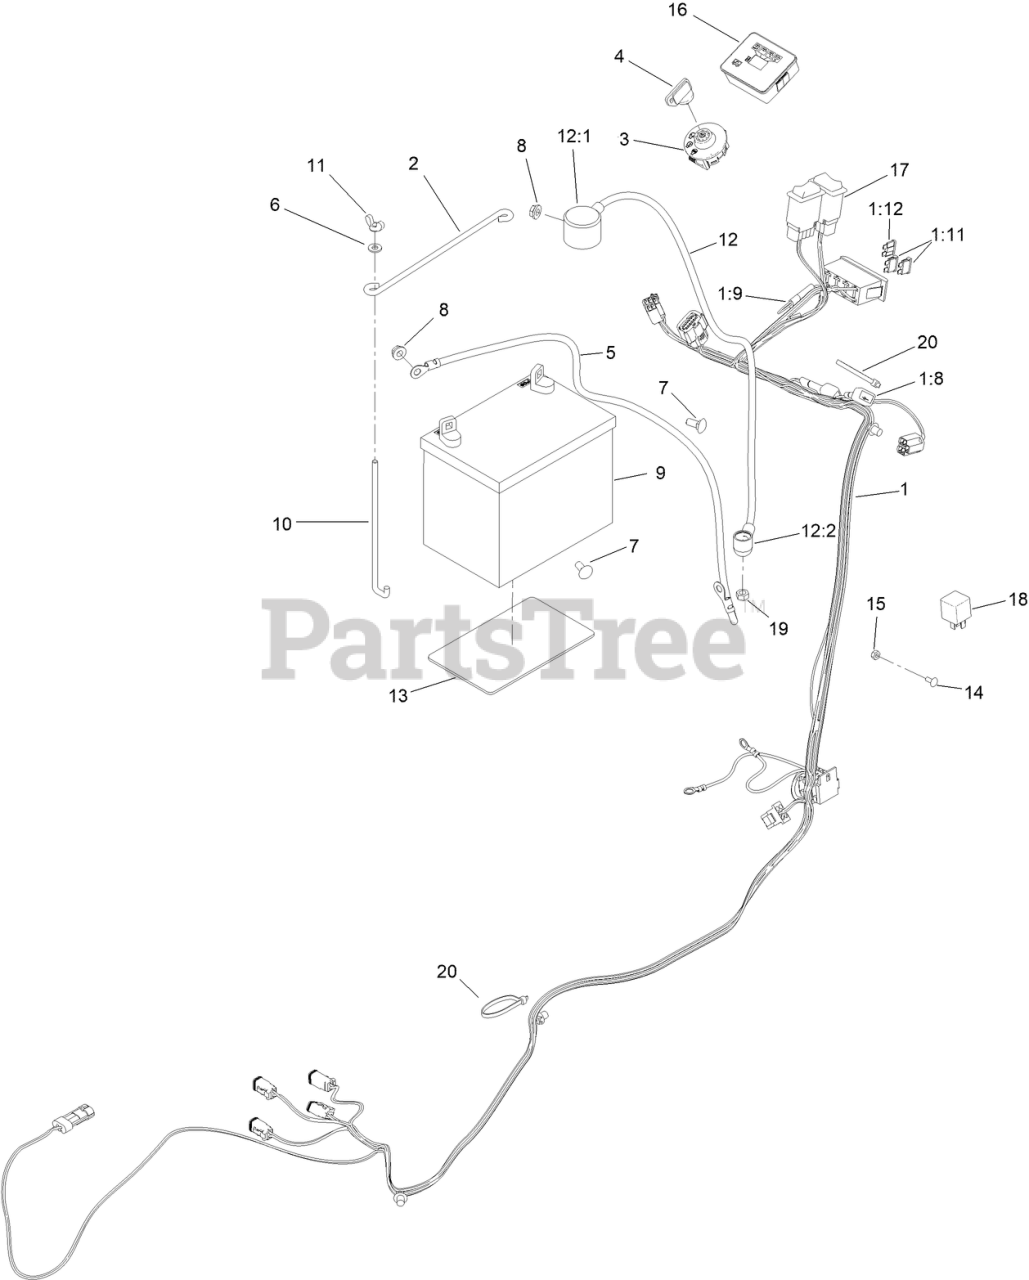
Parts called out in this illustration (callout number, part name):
1	HARNESS-WIRE, MUD BUGGY
1:9	CAP-TETHERED
1:11	FUSE-BLADE, 15 AMP
1:12	FUSE-BLADE, 7.5 AMP
2	ROD-HOLD DOWN, BATTERY
3	SWITCH-IGNITION
4	KEY-IGNITION
5	CABLE-BATTERY, NEGATIVE
6	WASHER-FLAT
7	BOLT-CARR
8	NUT-HF
9	BATTERY (340 CCA, WET)
10	POST-BATTERY
11	NUT-WING
12	POSITIVE BATTERY CABLE ASM
12:1	INSULATOR-BATTERY
12:2	INSULATOR-SOLENOID
13	PAD-SKID, ANTI
14	BOLT-CARR
15	NUT-LOCK, NI
16	MODULE, HOUR METER
17	SWITCH-ROCKER, 2 POLE
19	NUT-HEX
20	TIE-CABLE
